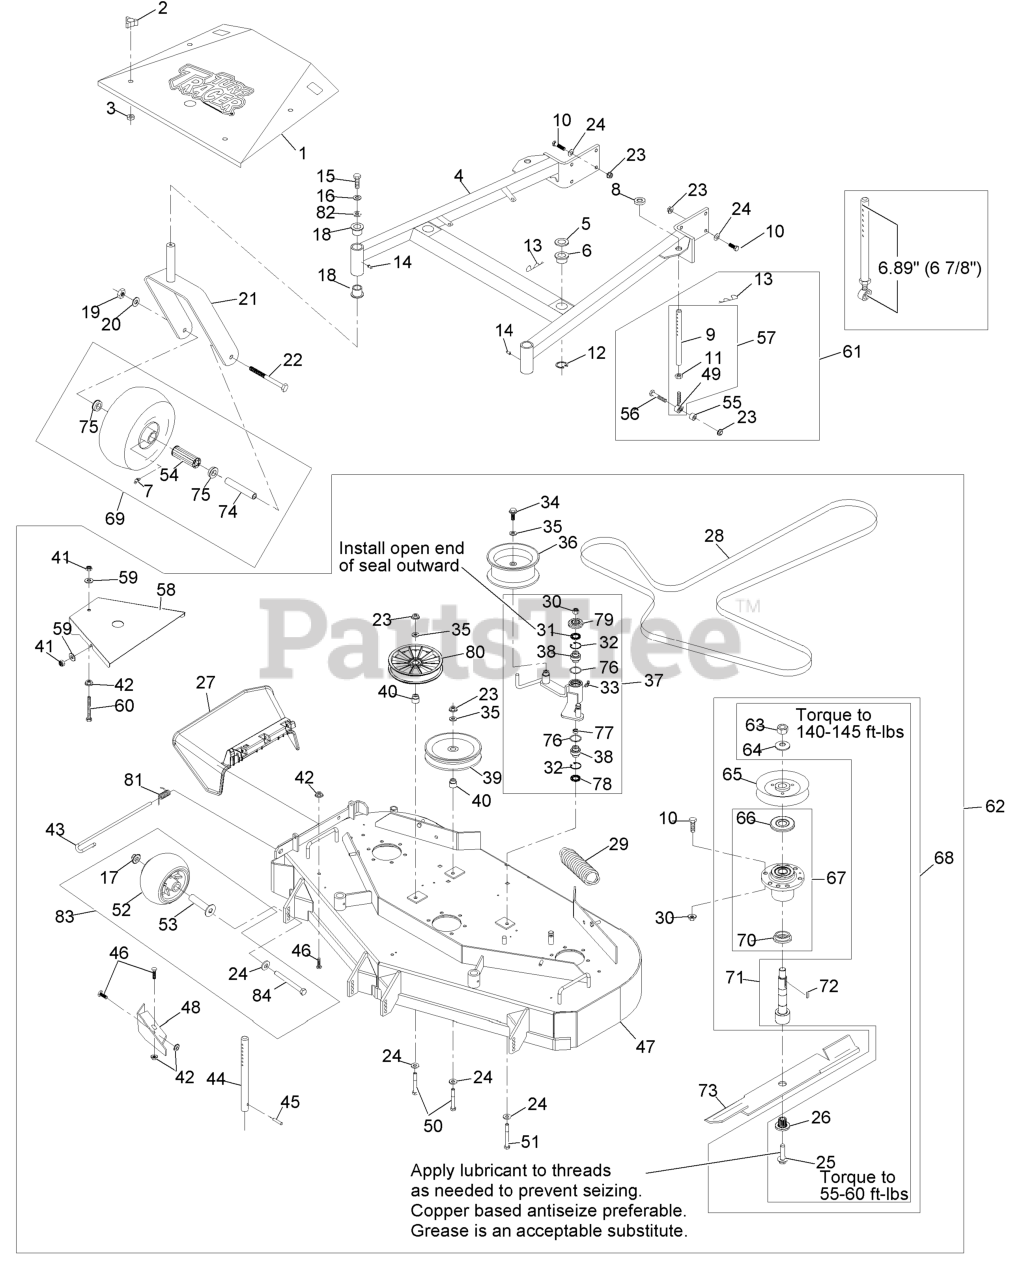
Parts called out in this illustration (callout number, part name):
1	ASM, SHIELD W/ DECALS, 48
2	KNOB-3 PRONG
4	DECK SUPPORT W/BSHGS 48"
5	SPACER-DECK SUPPORT
6	BUSHING-DECK
7	FITTING-GREASE
9	LINK,SUPPORT
10	SCREW-HH
11	NUT-HJ
12	RING-RETAINING
13	PIN,HAIR COTTER
14	FITTING-GREASE
15	SCREW-HH
16	WASHER-LOCK
17	Nut-Nyloc 3/8-16 Flg
18	BEARING-FLANGED
19	NUT-HH
20	WASHER-LOCK
22	SCREW-HH
23	NUT-HHF, WHIZ
24	WASHER-BELLEVILLE
25	SCREW,SEMS 1/2-20 X 2.19
26	BUSHING,SPLINED
27	CHUTE DEFLECTOR XRK M056
28	BELT - V, B
30	NUT-LOCK, NI
31	SEAL-LIP, SINGLE
32	RING-SNAP
33	FITTING-GREASE, 90 DEG
34	SCREW-HHF
35	WASHER-FLAT
36	IDLER-PULLEY, FLAT
37	KIT, DECK IDLER TTHP48&52
38	BEARING-SPHERICAL
39	PULLEY-IDLER
40	BUSHING-IDLER
41	NUT-LOCK, NI
43	PIN-CHUTE
44	ROD,DECK SUPPORT
46	SCREW-HH
47	ASM,DECK W/DECALS TTHP/MH
48	BAFFLE,DOGLEG
49	BALLJOINT
50	SCREW-HH
51	SCREW-HH
52	ROLLER-SCALP, ANTI
53	AXLE, ROLLER
54	BEARING
56	SCREW-HH
58	SHIELD,BELT
59	WASHER-FLAT
60	BOLT,TAP HH
61	KIT,SUPPORT LINK W/PIN
62	Assembly, Cutting Deck Complete
65	SHEAVE,W/HUB 5.72
66	GUARD-BEARING, TOP
67	KIT, CUTTER HOUSING
68	ASM, CUTTER HSG
69	KIT, SP CASTER WHEEL REPL
70	SPACER-GUARD, BOTTOM
71	KIT, SPLINED SPINDLE 103-
72	KEY-RECTANGLE
75	BUSHING
78	SEAL-LIP, DOUBLE
79	GUARD-TOP
80	PULLEY,IDLER 5"
81	SPRING, TORSION
83	KIT, ANTI-SCALP ROLLER
84	SCREW-HH 3/8-16 X 3 3/4 GR 8
